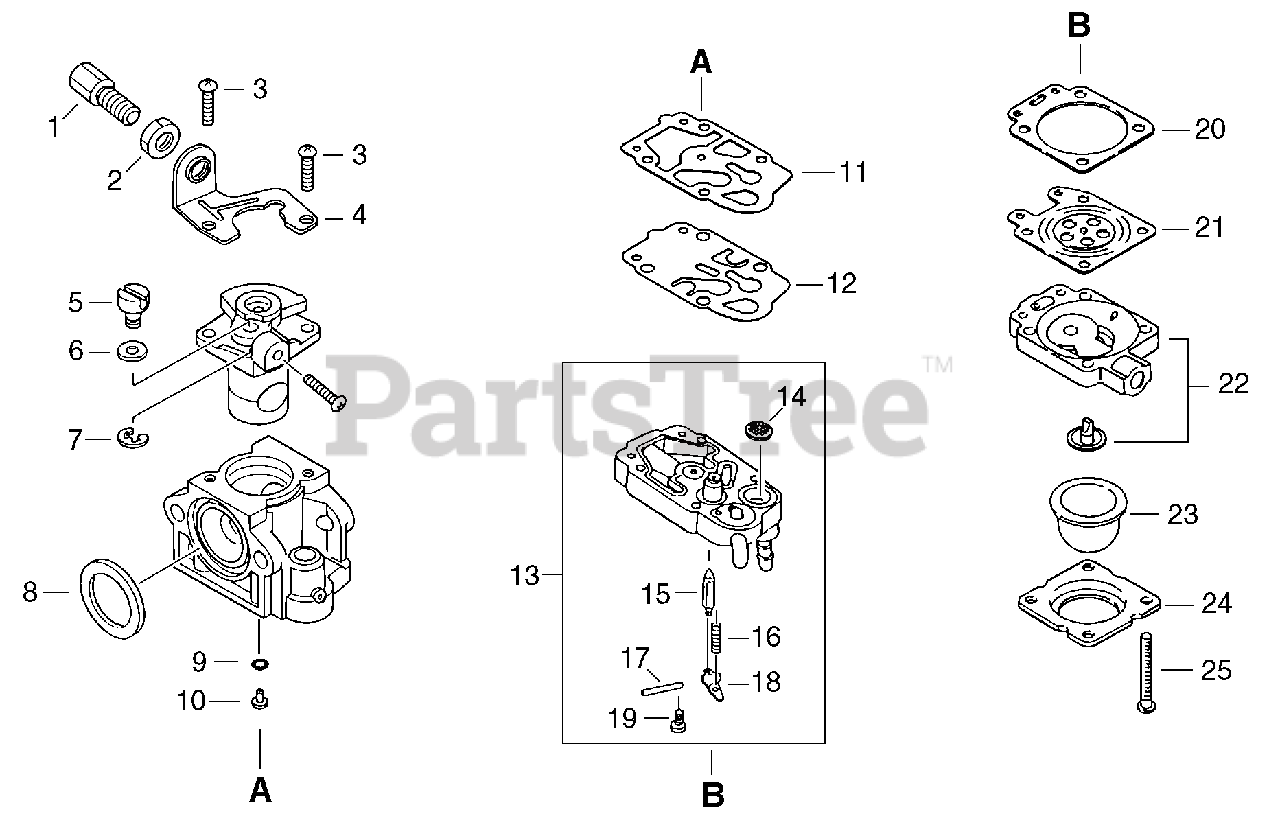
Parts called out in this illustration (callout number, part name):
1	ADJUSTER, THROTTLE CABLE
2	NUT, ADJUSTER LOCK M7
4	BRACKET, THROTTLE CABLE
8	RING, PACKING
10	JET, MAIN #37
11	GASKET, PUMP
12	DIAPHRAGM, FUEL PUMP
13	BODY ASSY, PUMP
14	SCREEN, FUEL INLET
15	VALVE, INLET NEEDLE
16	SPRING, METERING LEVER
17	PIN, METERING LEVER
18	LEVER, METERING
20	GASKET, METERING DIAPHRAGM
21	DIAPHRAGM, METERING
22	BODY ASSY, PURGE
23	BULB, PURGE
24	RETAINER, PURGE BULB
